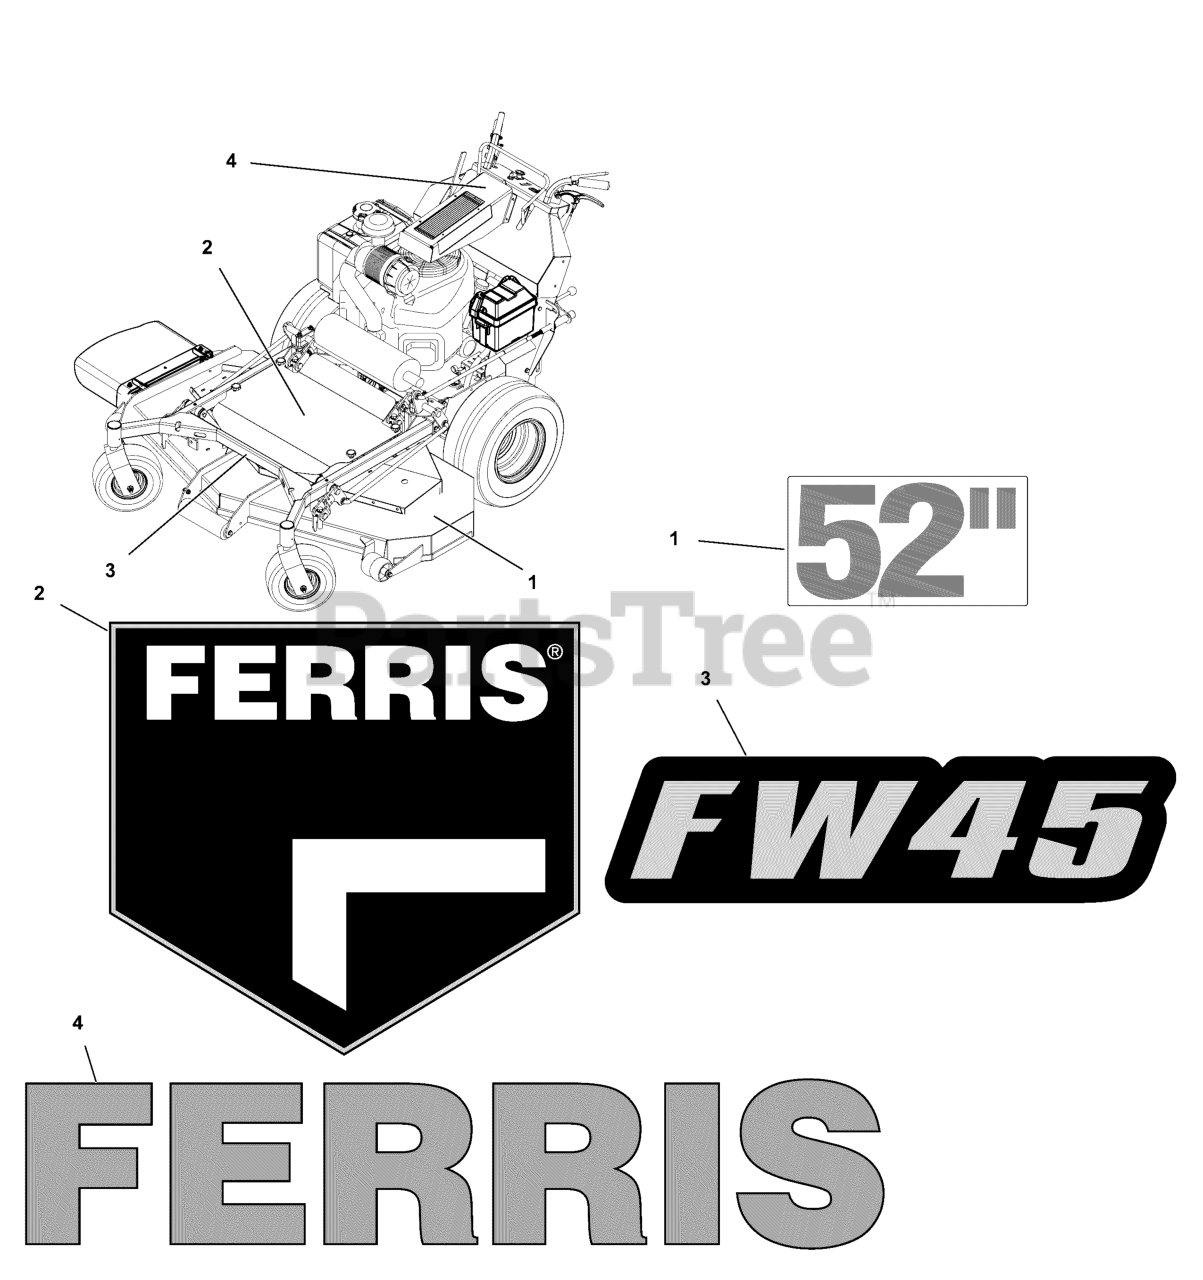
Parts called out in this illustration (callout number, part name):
1	DECAL, 61"
2	DECAL, BRAND
3	DECAL, MODEL, W45
4	DECAL, FERRIS TEXT, 5"
